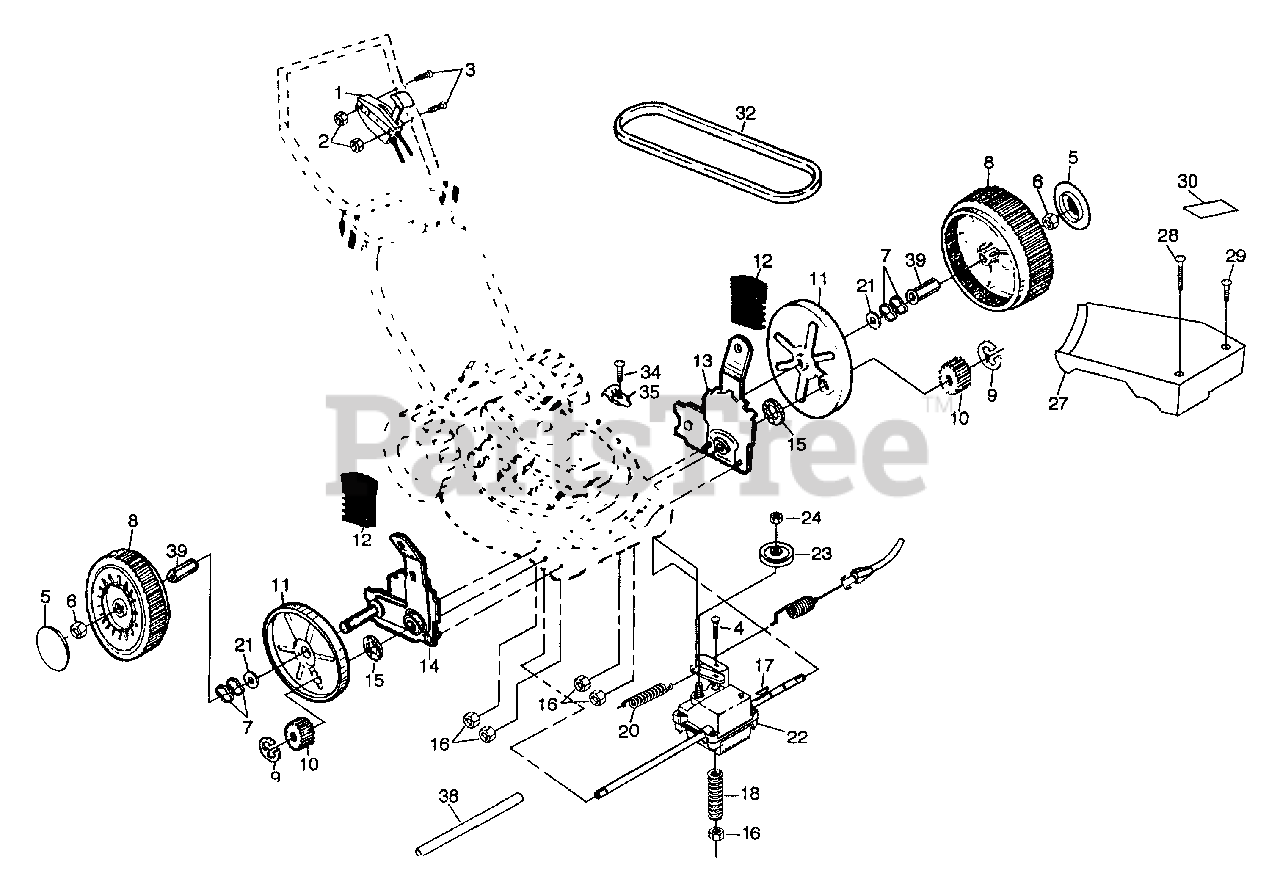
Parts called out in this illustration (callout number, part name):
1	Drive Control
2	Locknut #10-24
3	Pan Head Machine Screw
4	Carriage Bolt 1/4-20 x 2
6	Nut 3/8-16
7	Wave Washer
8	Wheel & Tire Assembly
11	Dust Cover
12	Selector Knob
13	Wheel Adjuster Assembly (Left)
14	Wheel Adjuster Assembly (Right)
15	Felt Washer
16	Locknut
17	Hi-Pro Key
22	Gear Case Assembly
23	Drive Pulley
24	Locknut
27	Drive Cover
28	Pan Head Machine Screw #10-24 x 2-3/4
29	Pan Head Machine Screw #10-24 x 1-3/4
30	Drive Cover Decal
32	V-Belt
34	Screw #10-24 x 1 /2
35	Cable Clip
38	Drive Shaft Cover
39	Wheel Bushing
